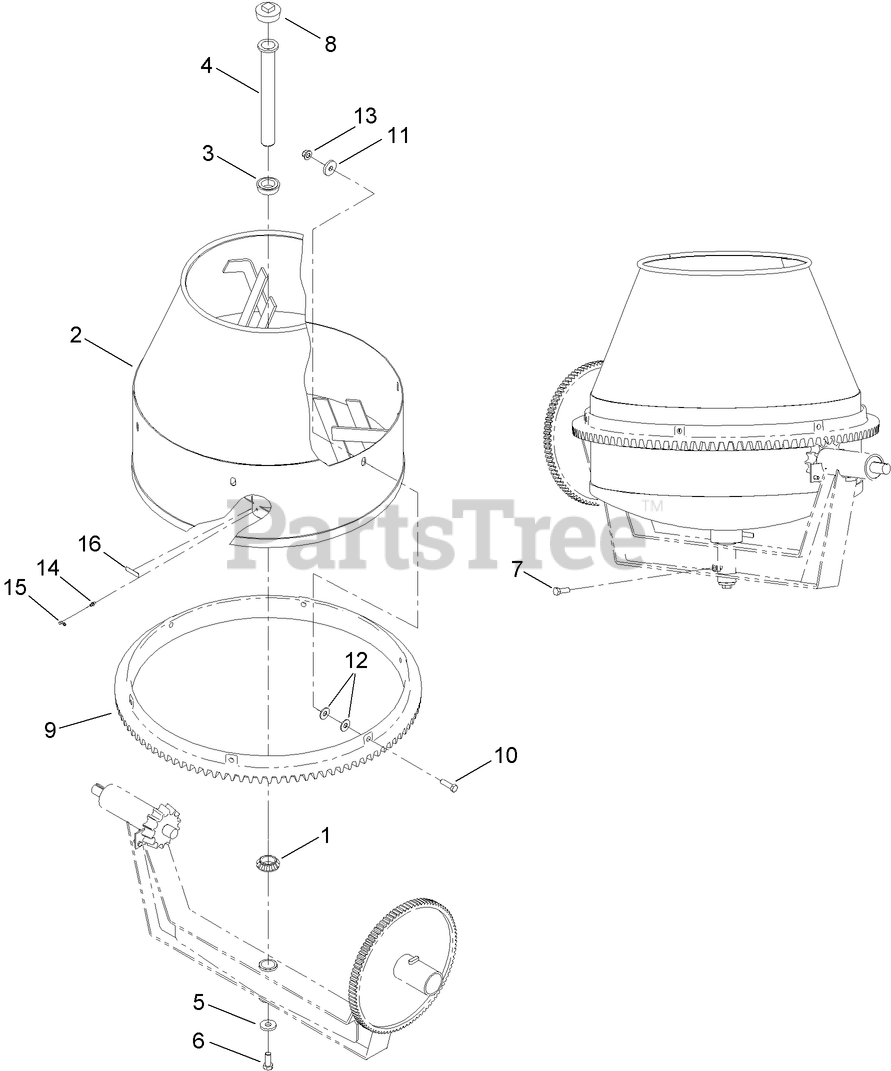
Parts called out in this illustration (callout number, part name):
1	BEARING-ROLLER
3	BEARING
4	SPINDLE
5	WASHER-FLAT
6	SCREW-HH
7	SCREW-HH
9	GEAR-RING
10	SCREW-HH
11	WASHER-FLAT
12	WASHER-FLAT
13	NUT-LOCK
14	FITTING
15	CAP-PLUG
16	DECAL-GREASE
